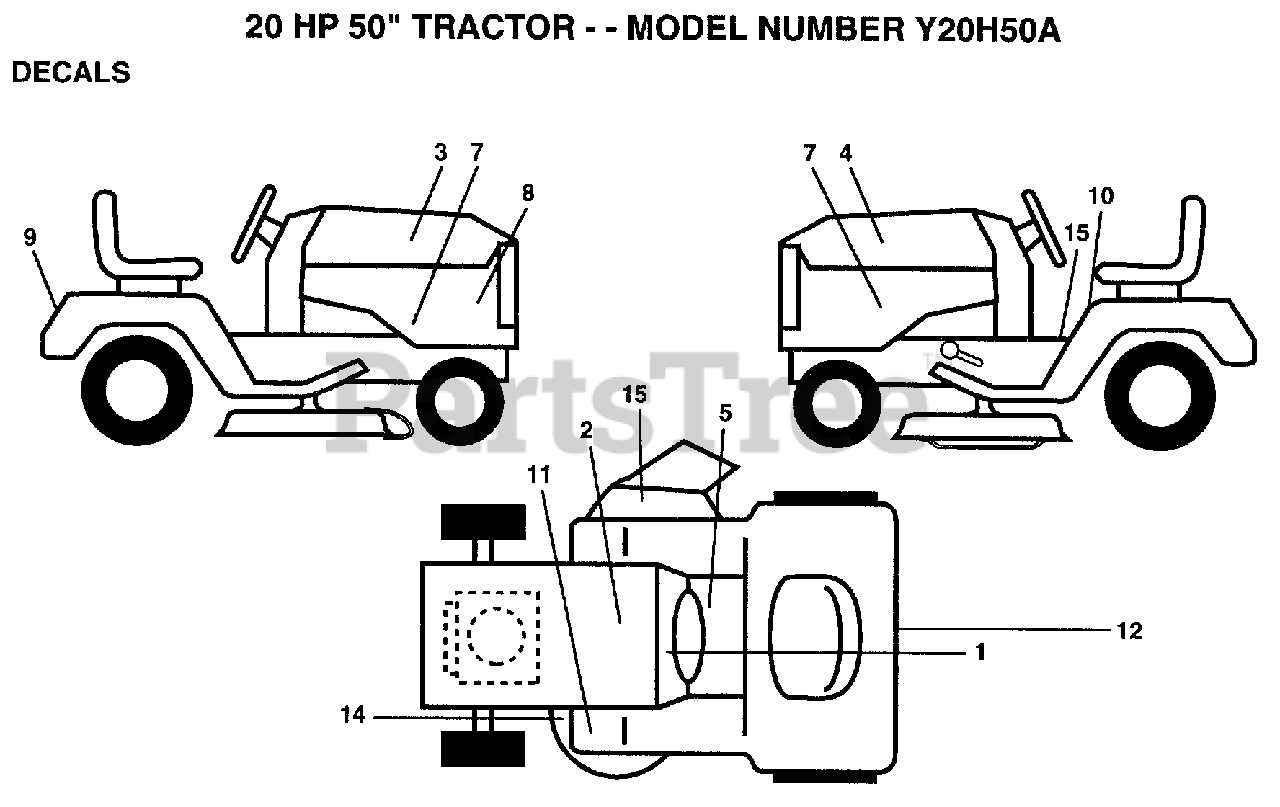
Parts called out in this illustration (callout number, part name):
1	DECAL.DASH.INSTR.
2	DECAL
4	DECAL HOOD LH
5	DECAL BRAK PARK
7	DECAL PANEL SIDE
8	DECAL SADLE HYDRO
10	DECAL CAUTION
11	DECAL T
12	DECAL D-BAR CNTRL
14	"DECAL.V.BELT.44"""
15	"DECAL, WARNING"
